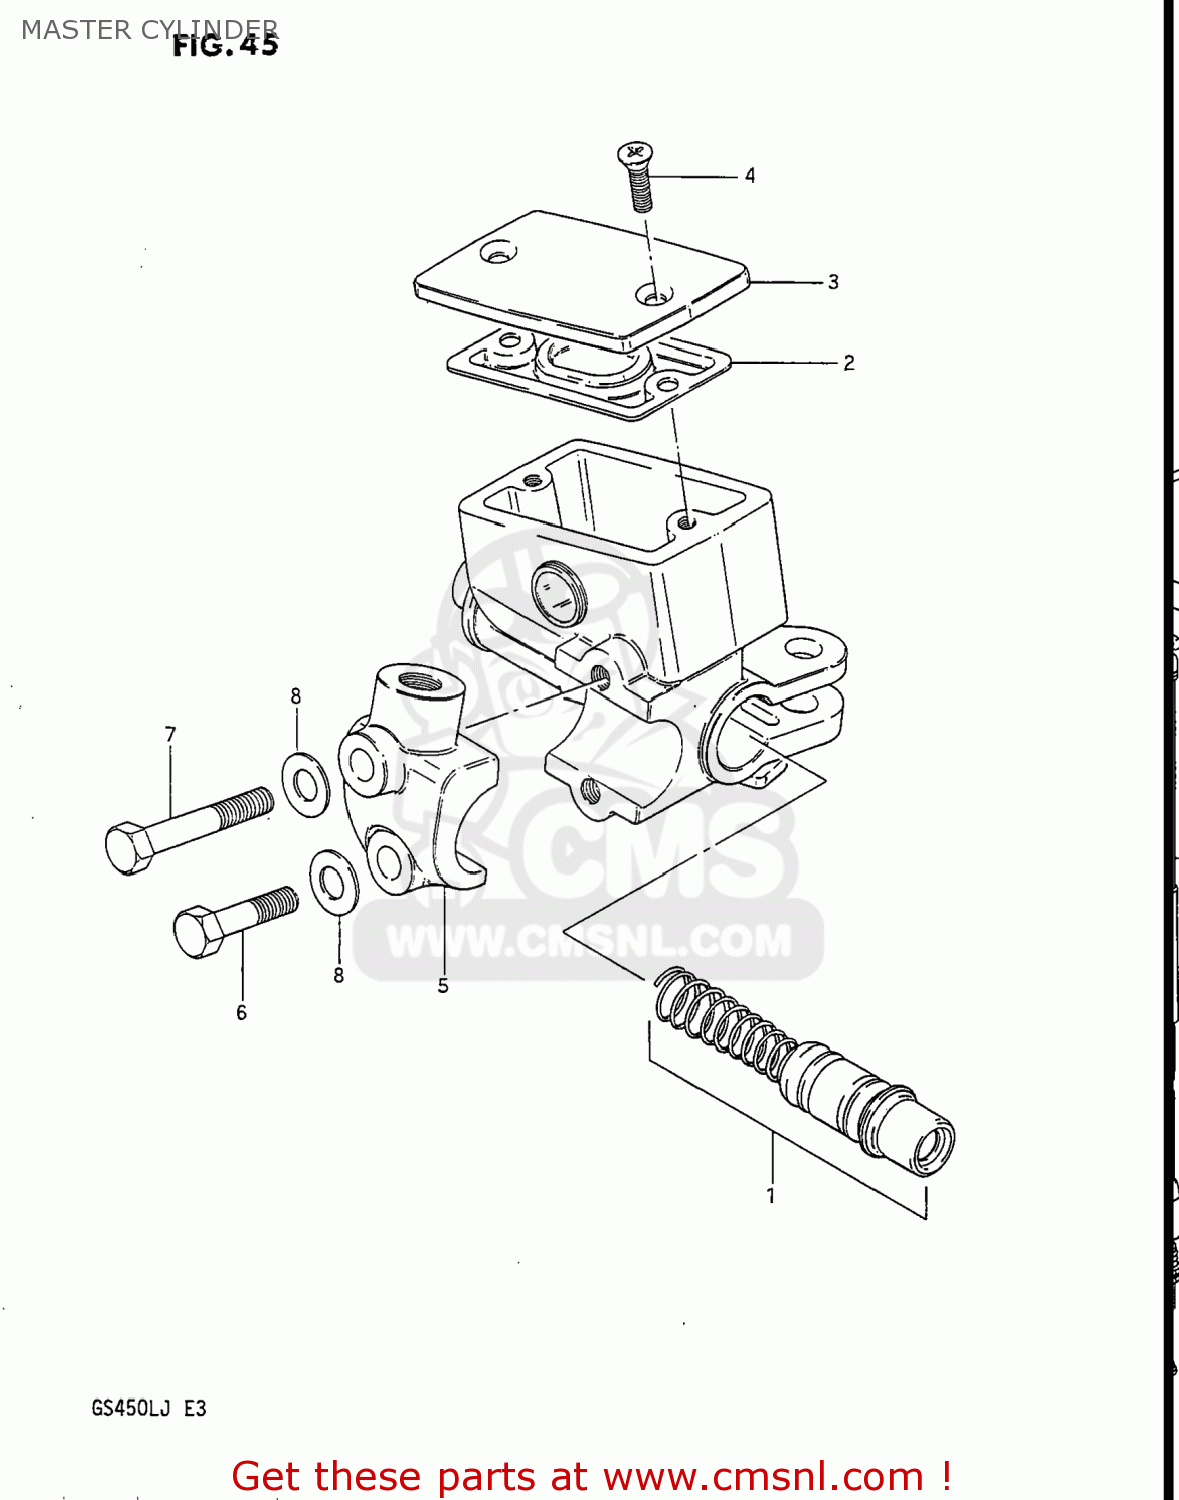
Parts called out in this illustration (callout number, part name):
1	PISTON & CUP SET
2	3
3	CAP
4	SCREW
5	HOLDER
6	BOLT
7	BOLT
8	WASHER
